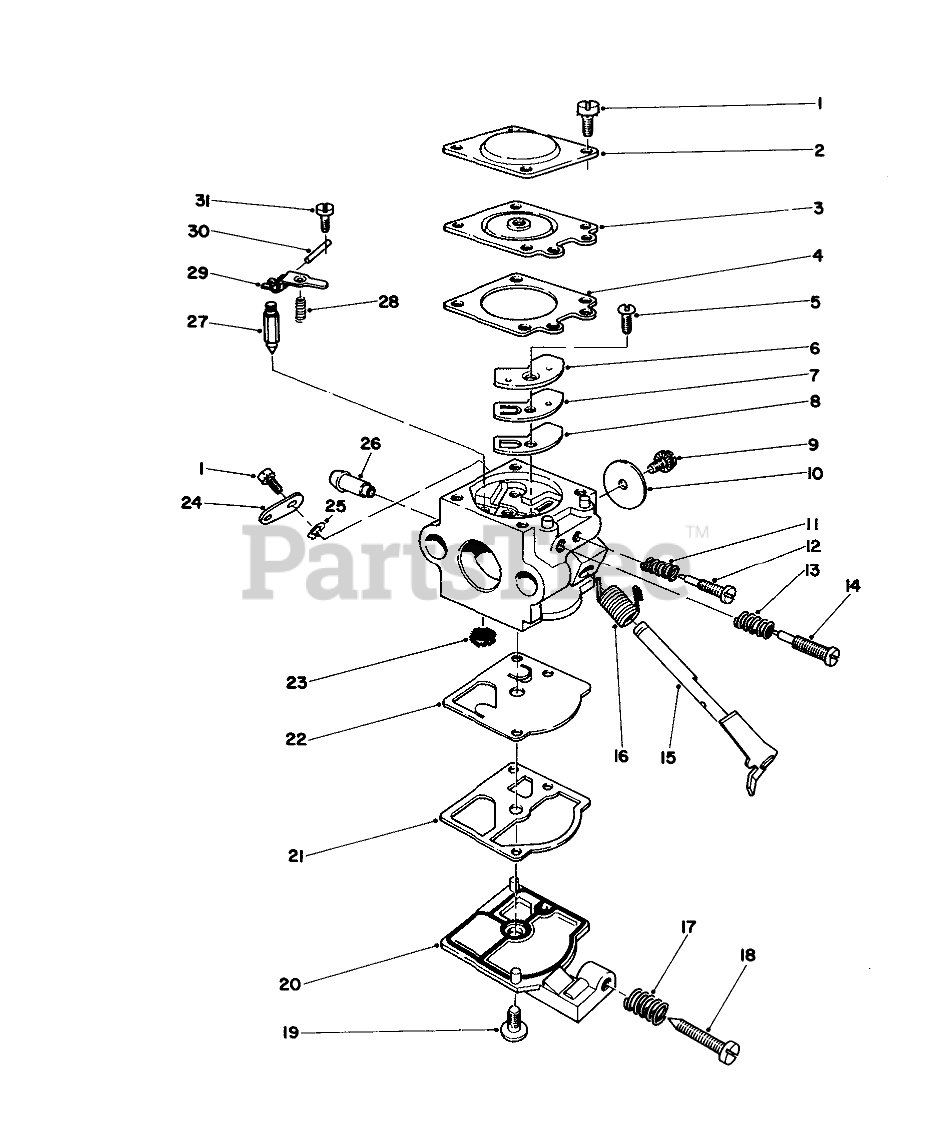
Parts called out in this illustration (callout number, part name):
1	Screw
2	Cover, Diaphragm
3	METERING DIAPHRAGM
4	Gasket, Diaphragm
5	Screw-Circuit Plate
6	Plate, Circuit
7	Diaphragm Circuit Plate
8	Gasket-Circuit Plate
9	Screw-Throttle Valve
10	Valve-Throttle
11	Spring, Needle
12	Needle-Idle
13	Spring, HS Needle
14	Needle, HS
15	Shaft Assembly-Throttle
16	Spring-Throttle Lever
17	Spring-Idle Screw
18	Screw-Idle Adjust
19	Screw
20	Cover-Fuel Pump
21	PUMP GASKET
22	Diaphragm Fuel Pump
23	Inlet Screen
24	Lever-Throttle
25	Ring-Throttle Retainer
26	Fitting Fuel Inlet
27	INLET NEEDLE VALVE
28	METERING LEVER SPRING
29	Lever Metering
30	Metering Lever Pin
31	Screw-Metering Pin
